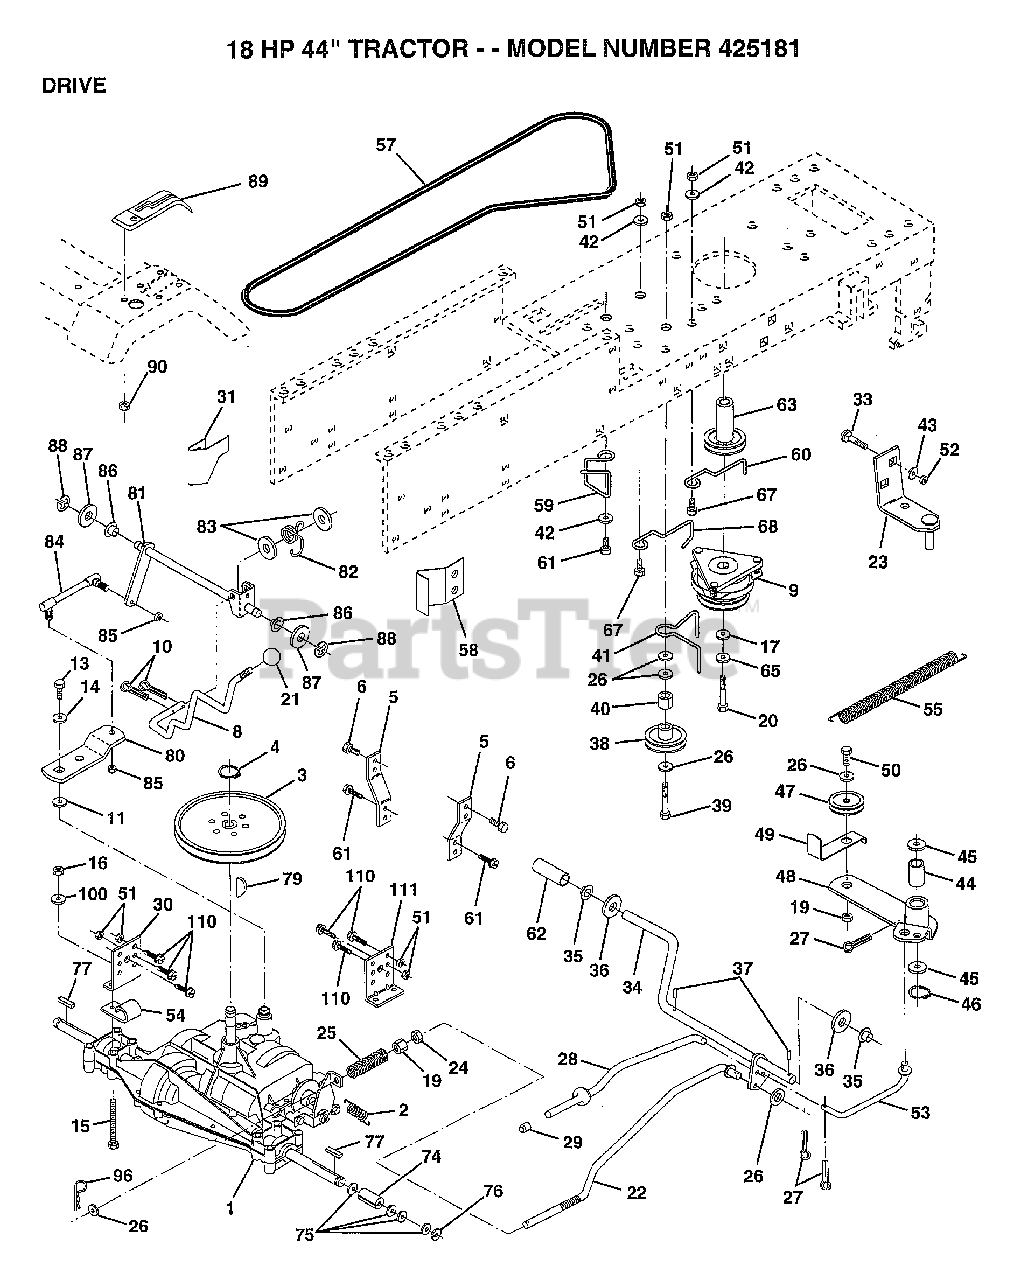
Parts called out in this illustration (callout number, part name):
1	TRANSAX. PRLES.
3	PULLEY TRANSAXLE
4	RING
5	STRAP TORQUE
6	SCREW
10	PIN COTTER 1/8
11	WASH-SHFT PLT LT
14	WASHER PM
15	BOLT HEX
16	NUT
17	WASHER
19	NUT
21	KNOB T (1/2-HOLE)
22	ROD BRAKE
23	BRACKET.ASM.MTG
24	NUT
25	"SPRING,ROD BRAKE"
26	WASHER
27	COTTER PIN
28	BRAKE PARK ROD
29	PLUNGER CAP T
30	BRKT TRANS LH
31	KEEPER BELT LH
33	BOLT
35	NYLON BEARING
36	WASHER LT
38	PULLEY.IDLER.FLAT
39	BOLT
40	SPACER T
41	BELT KEEPER LT
42	WASHER
43	WASHER T
44	"LY, BEARING"
45	WASHER LT
46	KLIP RING
48	ARM IDLER
49	RETAIN BELT
53	"LINK, CLUTCH T"
54	CLIP T
55	"SPRING, RETURN LT"
57	BELT.GRDRV.94.75
58	"KEEPER,BELT RH"
59	KEEPER BELT CNTSP
60	KEEPER BELT ENGLH
61	SCREW
62	PEDAL COVER T
63	PULLEY ENGINE
65	LOCKWASHER
67	BOLT
68	"KEEPER,BLT ENG LT"
74	SPACER HYT
75	WASHER
76	E RING HYT
77	SQ KEY STD
80	"ARM,SHIFT"
81	"SHAFT,SHIFTER"
82	"SPRING,TORSION"
83	WASHER
84	"ROD,TIE "
85	NUT 1/4-28
86	BUSHING
87	WASHER D
88	KLIP RING
89	CONSOLE SHIFTER
90	NUT
96	RETAINER M
100	WASHER M
111	BRKT TRANS RH
